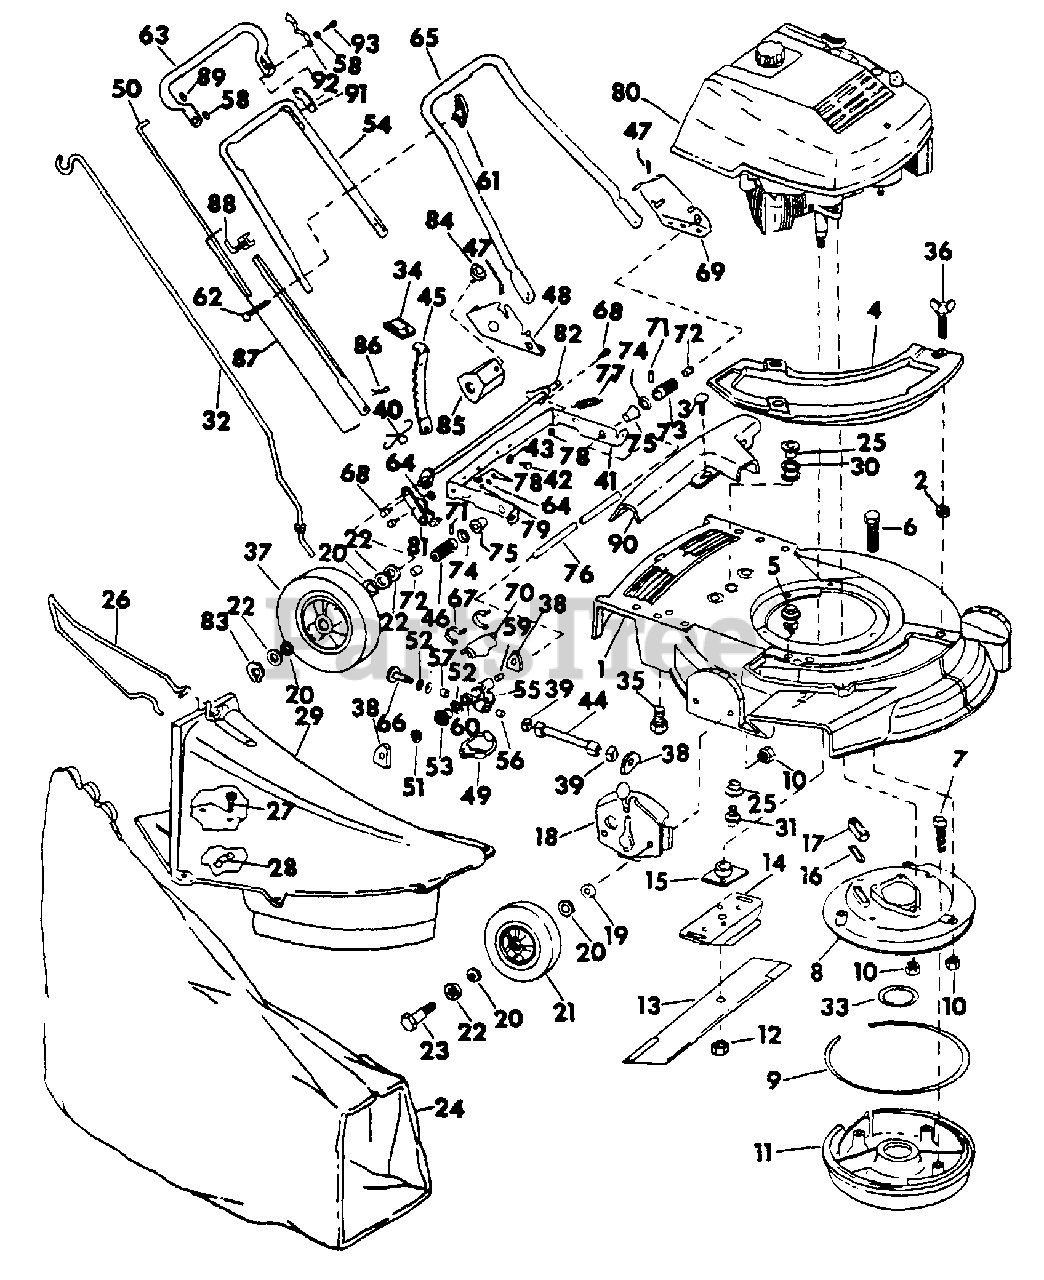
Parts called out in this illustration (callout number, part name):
1	HOUSING ASSY. 21IN.
2	NUT, GROMMET
3	SCREW, HEX-HD
4	COVER, CHUTE OPENING
5	SCREW, SHOULDER
6	SCREW, MUFFLER PLT TO HSG
7	SCREW, MUFFLER TO PLATE
8	PLATE, MUFFLER
9	GASKET, MUFFLER OUTSIDE
11	COVER, MUFFLER
13	BLADE, 21 IN
14	STIFFENER, BLADE
15	COLLAR & PLATE
16	GASKET, EXHAUST
17	SLEEVE, EXHAUST GASKET
18	ADJUSTMENT, HEIGHT
20	WASHER, FELT
21	WHEEL AND TIRE - 6 IN FRONT
22	WASHER, WHEEL BOLT HD
23	BOLT, WHEEL FRT SHOULDER
25	SPACER, FLANGED
26	GUARD, WHEEL
29	CHUTE ASSY
32	ROD, GRASS BAG
33	GASKET, MUFFLER INSIDE
35	SCREW, HANDLE BRACKET
36	SCREW, WING
37	WHEEL & TIRE, 8 IN. REAR
40	SPRING, HEIGHT ADJ
45	LEVER, HGT ADJ
46	ROLLER, DRIVE RH
48	BRACKET, HANDLE RH
49	COVER, GEAR BOTTOM
50	ROD, CONTROL
51	WASHER, FELT
52	WASHER, THRUST
53	GEAR, DRIVEN
54	HANDLE, CENTER
55	BRACKET & BRG ASSY
56	BEARING, NEEDLE
57	BEARING, NEEDLE
59	BEARING, NEEDLE
60	BEARING, NEEDLE
63	HANDLE & GRIP
65	HANDLE, BOTTOM
66	GEAR, DRIVE
67	CLAMP, COVER
68	BOLT, SHOULDER
69	BRACKET, HANDLE LH
70	COVER, GEAR TOP
71	PIN, ROLLER TO SHAFT
72	PLUG, ROLLER GREASE
73	ROLLER, DRIVE LH
74	WASHER
75	SLEEVE & BEARING
80	ENGINE, IH
85	GUARD, ROLLER
87	LEVER ASSY, CONTROL
89	NUT, PUSH
90	COVER, DRIVE
92	KNOB & SPRING, LOCKOUT
93	BOLT, SHOULDER
